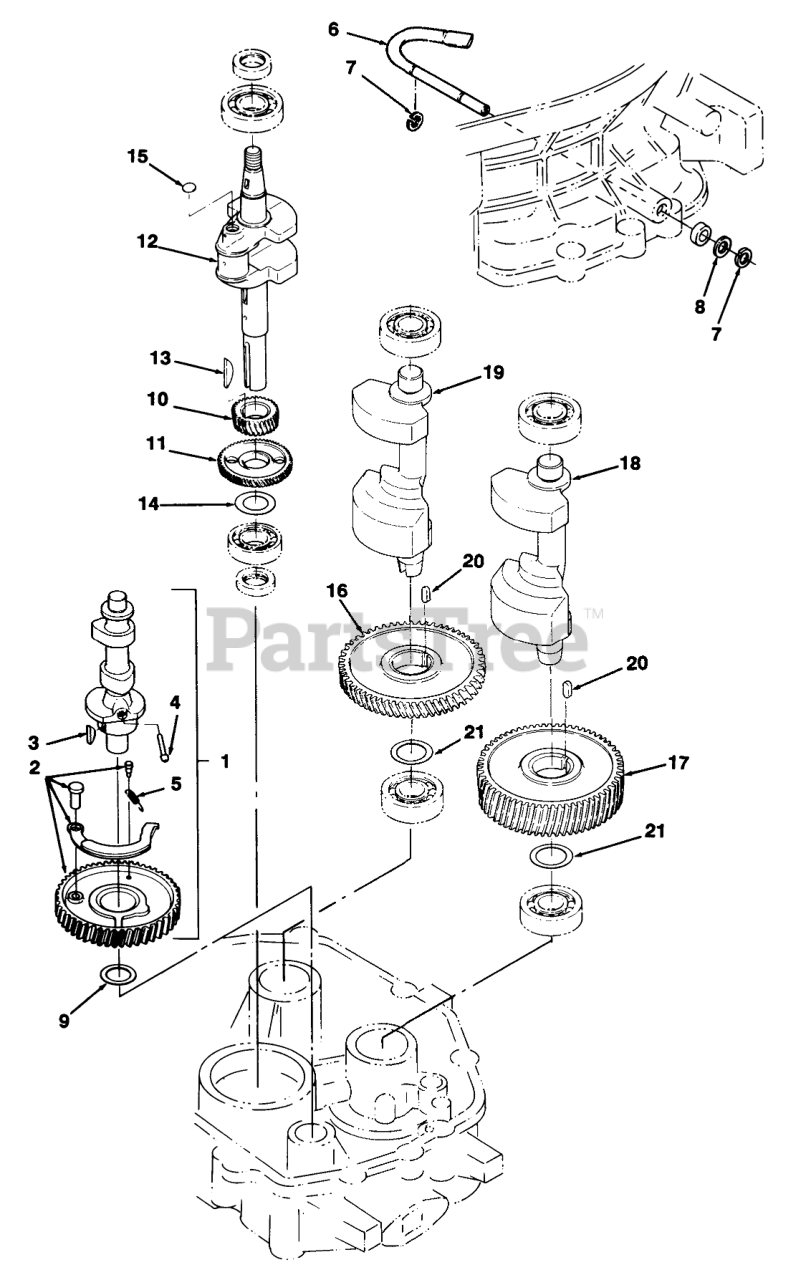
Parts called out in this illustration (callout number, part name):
1	Camshaft shaft Assembly (Incl. Ref. #2-5)
2	CAMGEAR ASS'Y
3	KEY-CAMGEAR
4	PIN-DECOMPRESSION
5	SPRING-DECOMPRESSION
6	SHAFT-GOVERNOR LEVER
7	CLIP-RETAINER
8	WASHER-FLAT
9	SHIM-CAMSHFT 0.5MM
10	GEAR-CRANKSHAFT
11	GEAR-BALANCER
12	Crankshaft
13	KEY-CRANKSHAFT GEAR
14	SHIM-CRANKSHFT 0.2MM
15	PLUG-EXPANSION
16	GEAR-BALANCER
17	GEAR-BALANCER
18	SHAFT-BALANCER
19	SHAFT-BALANCER
20	KEY-BALANCER GEAR
21	SHIM-BAL SHAFT 0.5MM
